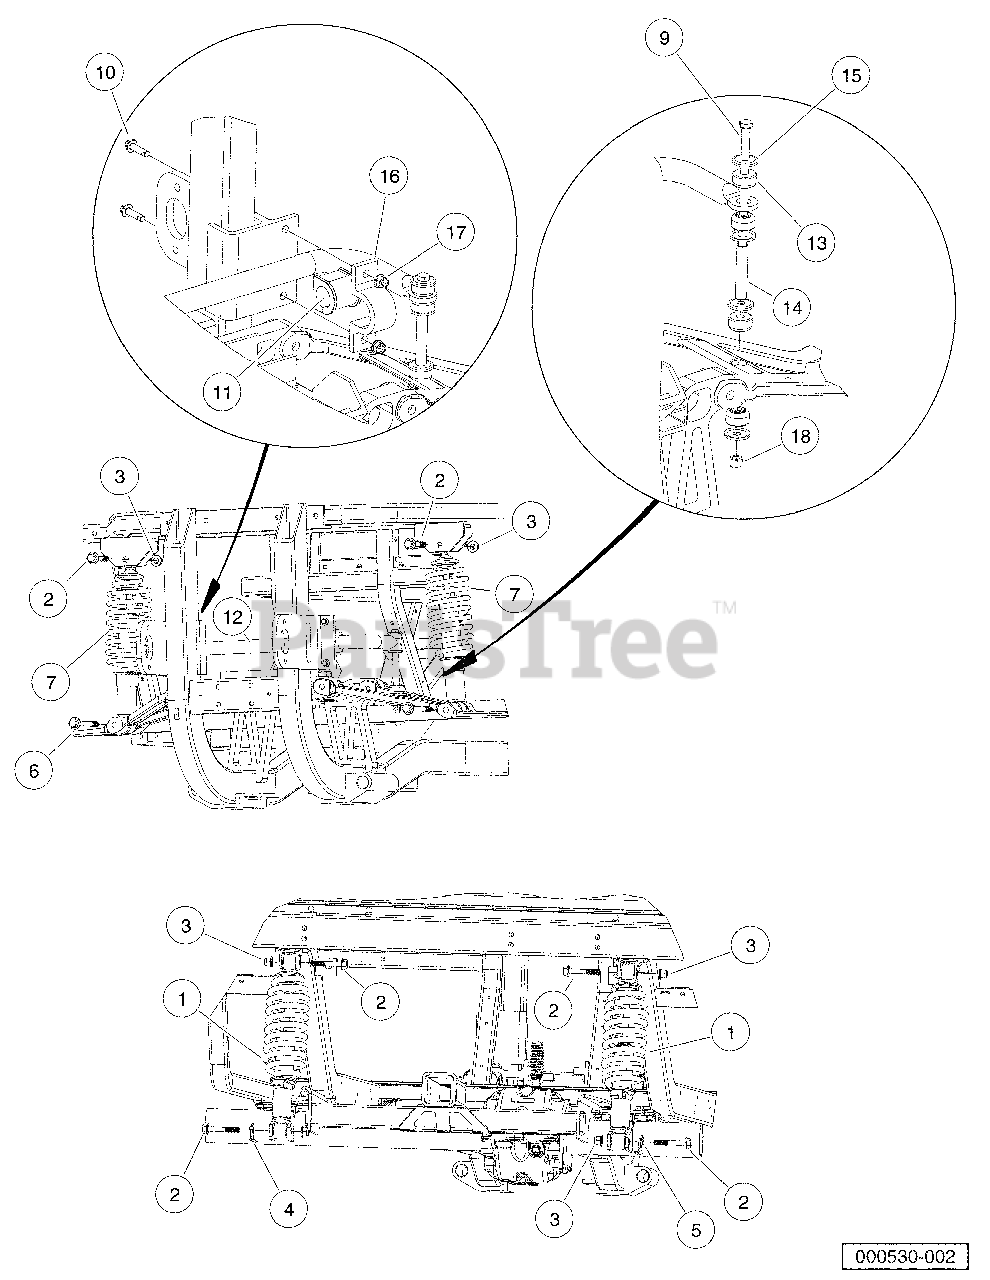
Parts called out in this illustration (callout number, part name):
1	Shock, Coil Over, Rear HD
2	Bolt, Flange Head, M12 X 1.75 X 70
3	Nut Flg, M12x1.75, Nylon Gr 10
4	Brkt, Line, Hyd, Shk Mnt, Drv
5	Brkt, Line, Hyd, Shk Mnt, Pass
6	Bolt Flg, M12x1.75x100, Patch.
7	Asm, Coil & Shock, Frt
8	Instl, Bar, Antisway, Wide Frt
9	Screw, 3/8-16 X 7.00 Hex Cap
10	Bolt, Flange Head, M8 X 30.0.
11	Bushing, Anti-Sway Bar, 1-1/8
12	Bar, Sway, Formed.
13	Bushing, Link
14	Sleeve, Link.
15	Washer, Cup, Bushing.
16	Bracket, Anti-Sway Bar
17	Lock Nut, Flg M8 X 1.25 Nylon.
18	Locknut, 3/8-16 Hex
